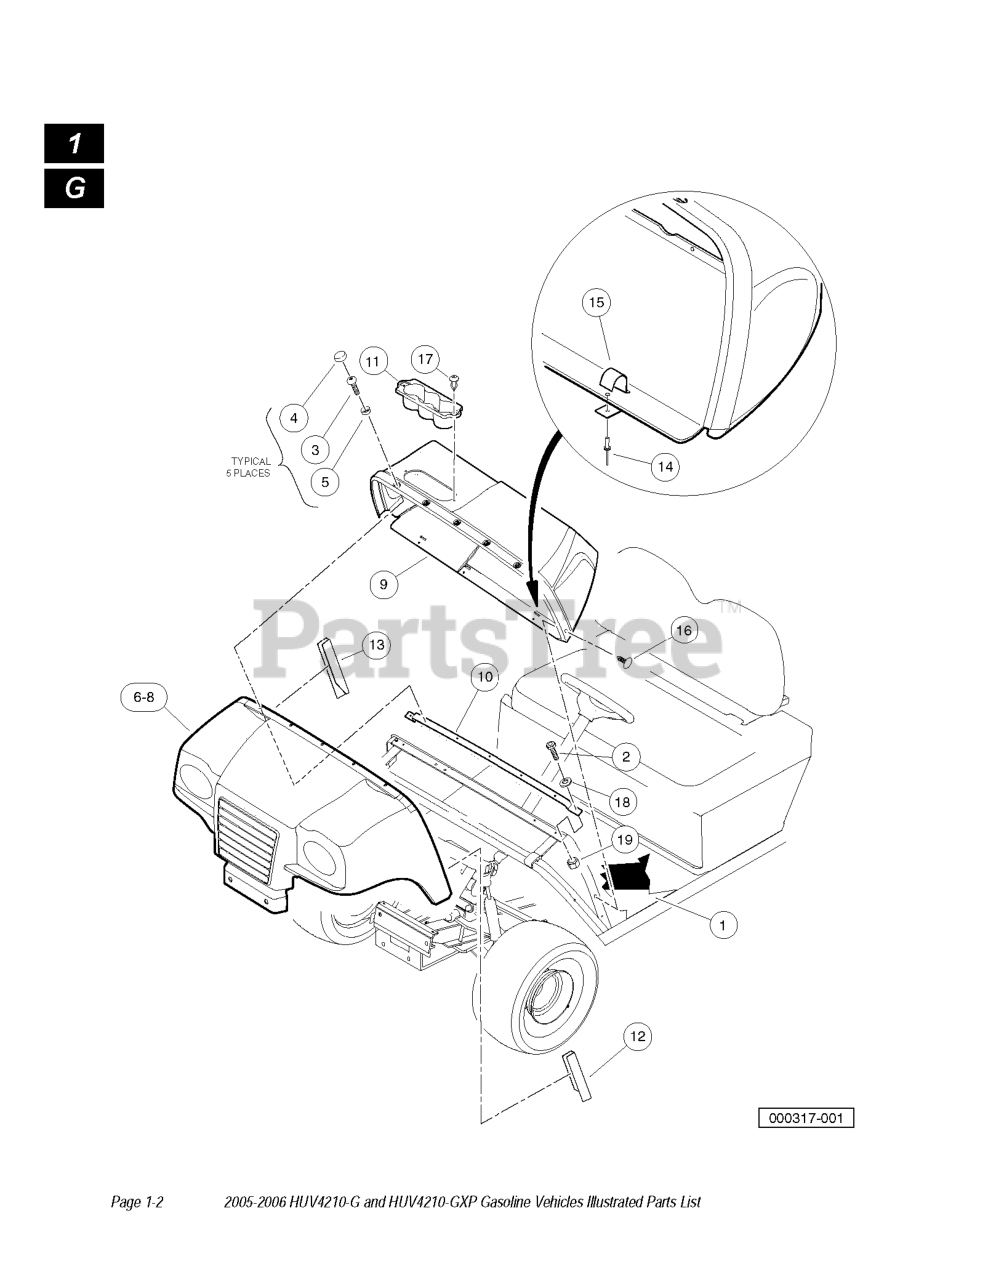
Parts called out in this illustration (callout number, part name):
1	FLOORMAT - DEBADGED
2	SCREW, 1/4-20 X .750 HEX HEAD
3	SCREW 1/4-20X.75 TORX PN HD
4	CAP 1/4" PLASTIC SCREW HEAD
5	WASHER 1/4 ID SCALLOPED PLAST
6	COWL, 4210, ORANGE
7	COWL, 4210, CAMO
9	DASH - H2 FORMED
10	UPPER COWL SUPPORT
11	OBJECT HOLDER
12	COWL COVER, DRIVER
13	COWL COVER, PASSENGER
15	CLIP, DASH
16	PUSH PIN, BLACK
17	SCREW, TUFLOK PANEL, 1/4
18	WASHER 1/4 FLAT
19	LOCKNUT, 1/4-20 NYLON INSERT
